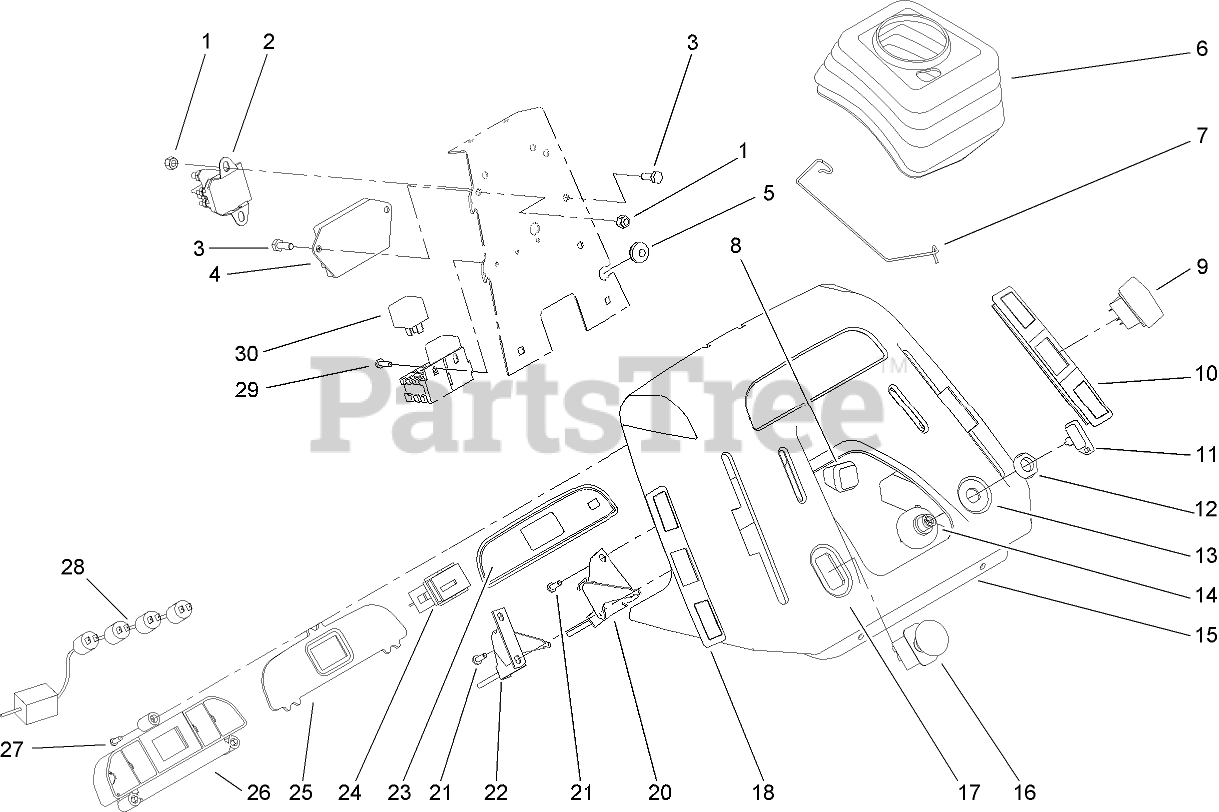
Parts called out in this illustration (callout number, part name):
1	NUT-LOCK, NI
2	SOLENOID-STARTER
3	SCREW-HH
4	MODULE-NMIR, LOW BATTERY
5	GROMMET-RUBBER
6	BOOT-STEERING
7	CLIP-BOOT
9	SWITCH-CRUISE
10	COVER-SLOT, RH
11	KEY-IGNITION
13	DECAL-THROTTLE, IGNITION
14	SWITCH-IGNITION
16	SWITCH-PTO
17	DECAL-PTO / CHOKE
18	COVER-SLOT, LH
20	CONTROL-THROTTLE (TWIN)
22	CHOKE CONTROL ASM
23	DECAL-LENS, DASH
24	HOURMETER
25	LENS-DASH
26	HOUSING-LIGHT, INDICATOR
27	SCREW
28	HARNESS-4 LAMP
29	SCREW-PPHTF
30	RELAY
